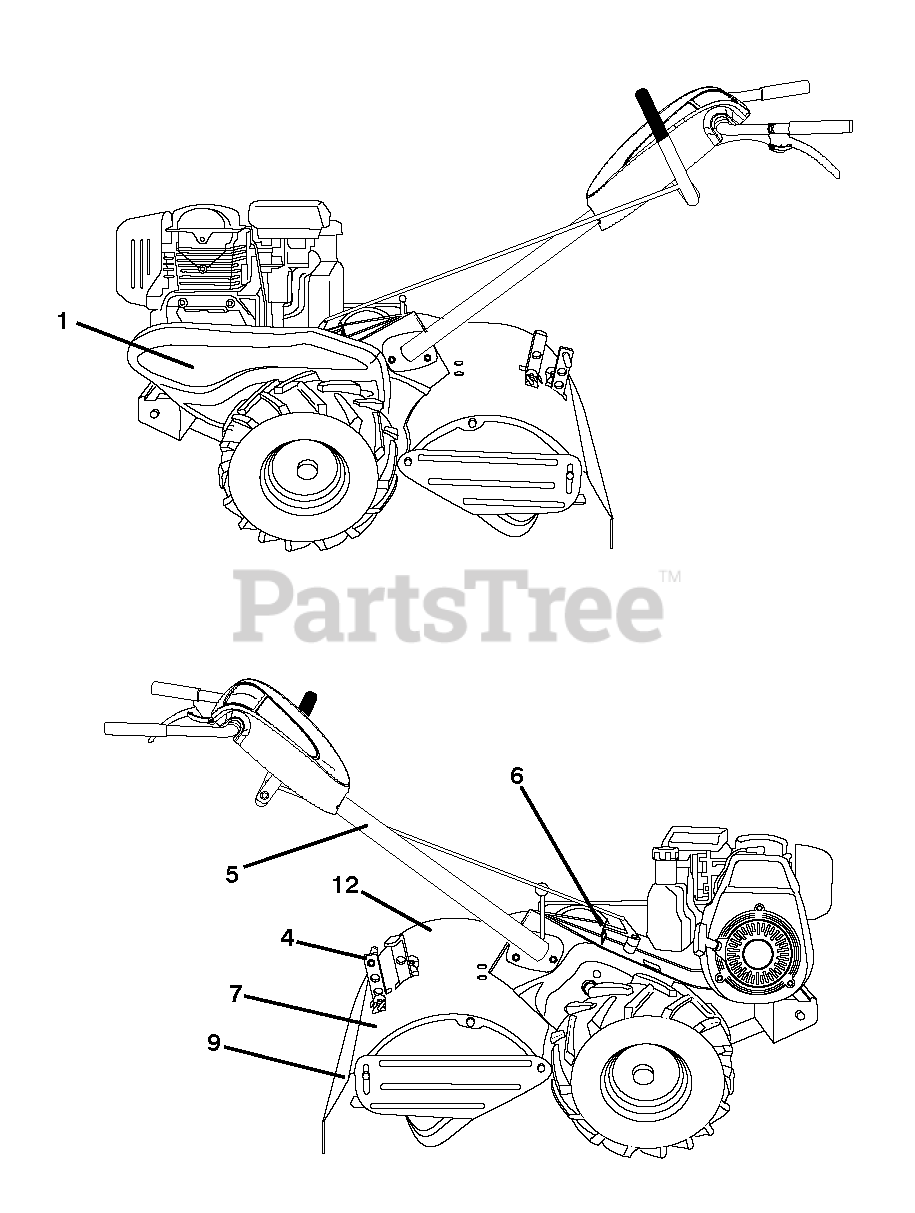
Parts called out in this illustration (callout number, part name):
1	RP.DECAL.BADGE.170MM.TEXTLOGO
4	DECAL.SHIELD.TN.DRT17.HUSQ
5	DECAL TI (2 2)
6	DECAL.SHIFT.INDICATOR.DRT
7	DECAL.REVERSE.HUSQ.TILLER
9	DECAL.DRT.WARN.ENG/F
12	DECAL.FOWARD.HUSQ.TILLER
